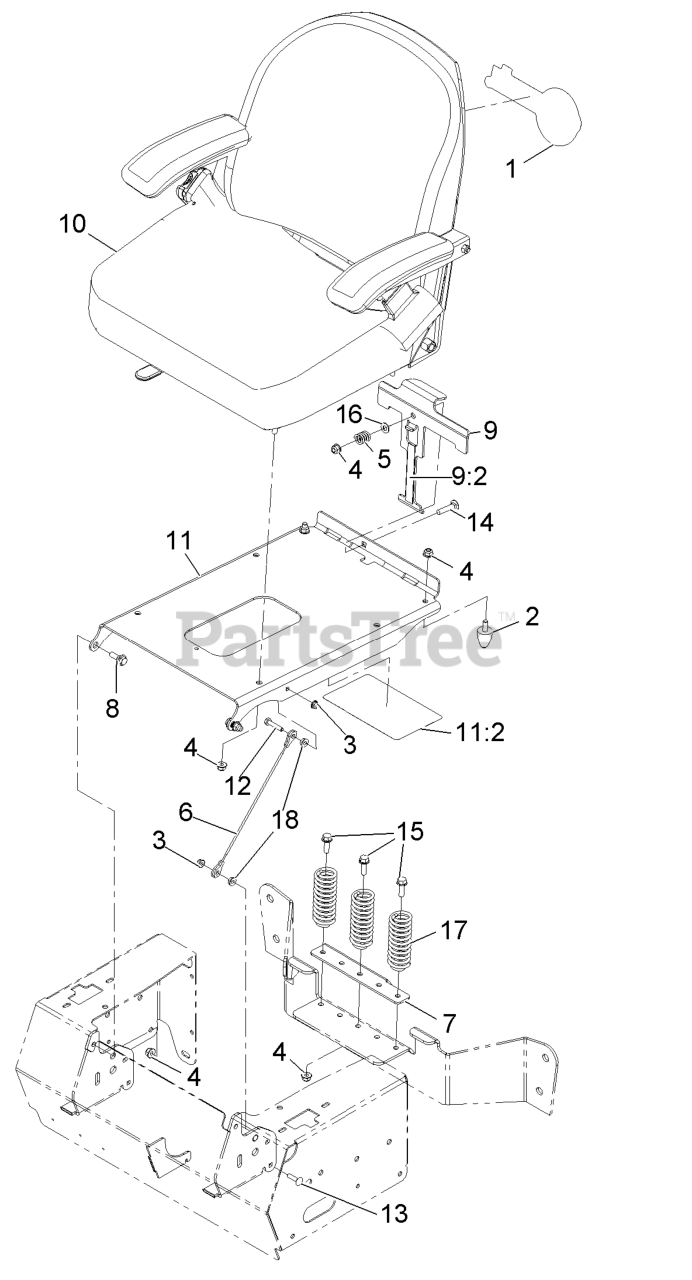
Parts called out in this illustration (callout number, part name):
1	DECAL,EXMARK LOGO
2	BUMPER-SEAT
4	NUT-HF, NI
5	SPRING-COMPRESSION
6	CABLE-STOP, SEAT
7	CATCH,SEAT LATCH
8	SCREW-SHOULDER
9	ASM-SEAT LATCH
9:2	STRIP-POLY WEAR
11	PLATE, SEAT W/DECALS
11:2	DECAL-SERVICE AID
12	SCREW-HH
13	SCREW-CARR
14	BOLT-CARR
15	SCREW-HHF
16	WASHER-PLAIN
17	SPRING-COMPRESSION
